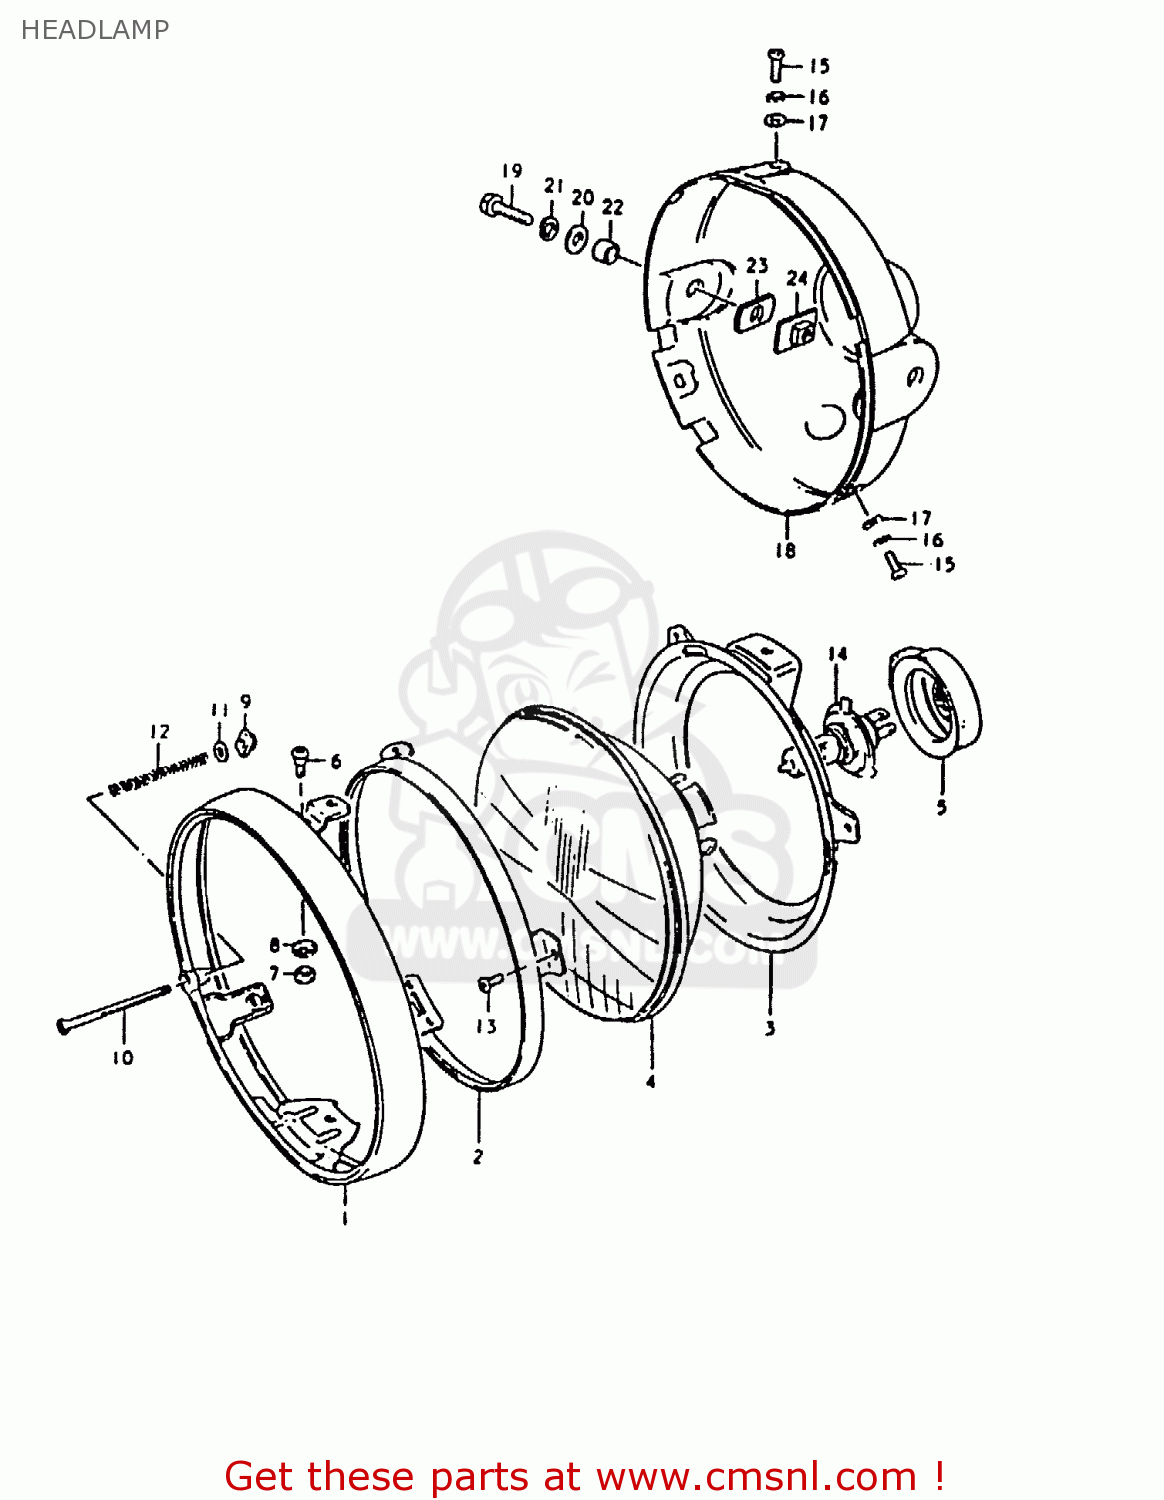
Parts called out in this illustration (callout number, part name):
1	RIM
2	RETAINER
3	RING,HEADLAMP UNIT
4	LAMP UNIT
5	COVER,HEADLAMP SOCKET
6	SCREW
7	NUT,ADJUSTING
8	SPACER
9	NUT
10	SCREW,HEADLAMP ADJUST
11	WASHER
12	SPRING,HEADLAMP ADJUST
13	SCREW
14	BULB(12V60/55W,H4)
15	SCREW
16	WASHER,LOCK
17	WASHER
18	HOUSING,HEADLAMP(BLACK)
19	BOLT
20	WASHER
21	LOCK WASHER
22	SPACER (8.8X12X7)
23	CUSHION
24	PLATE,HEADLAMP HOUSING
